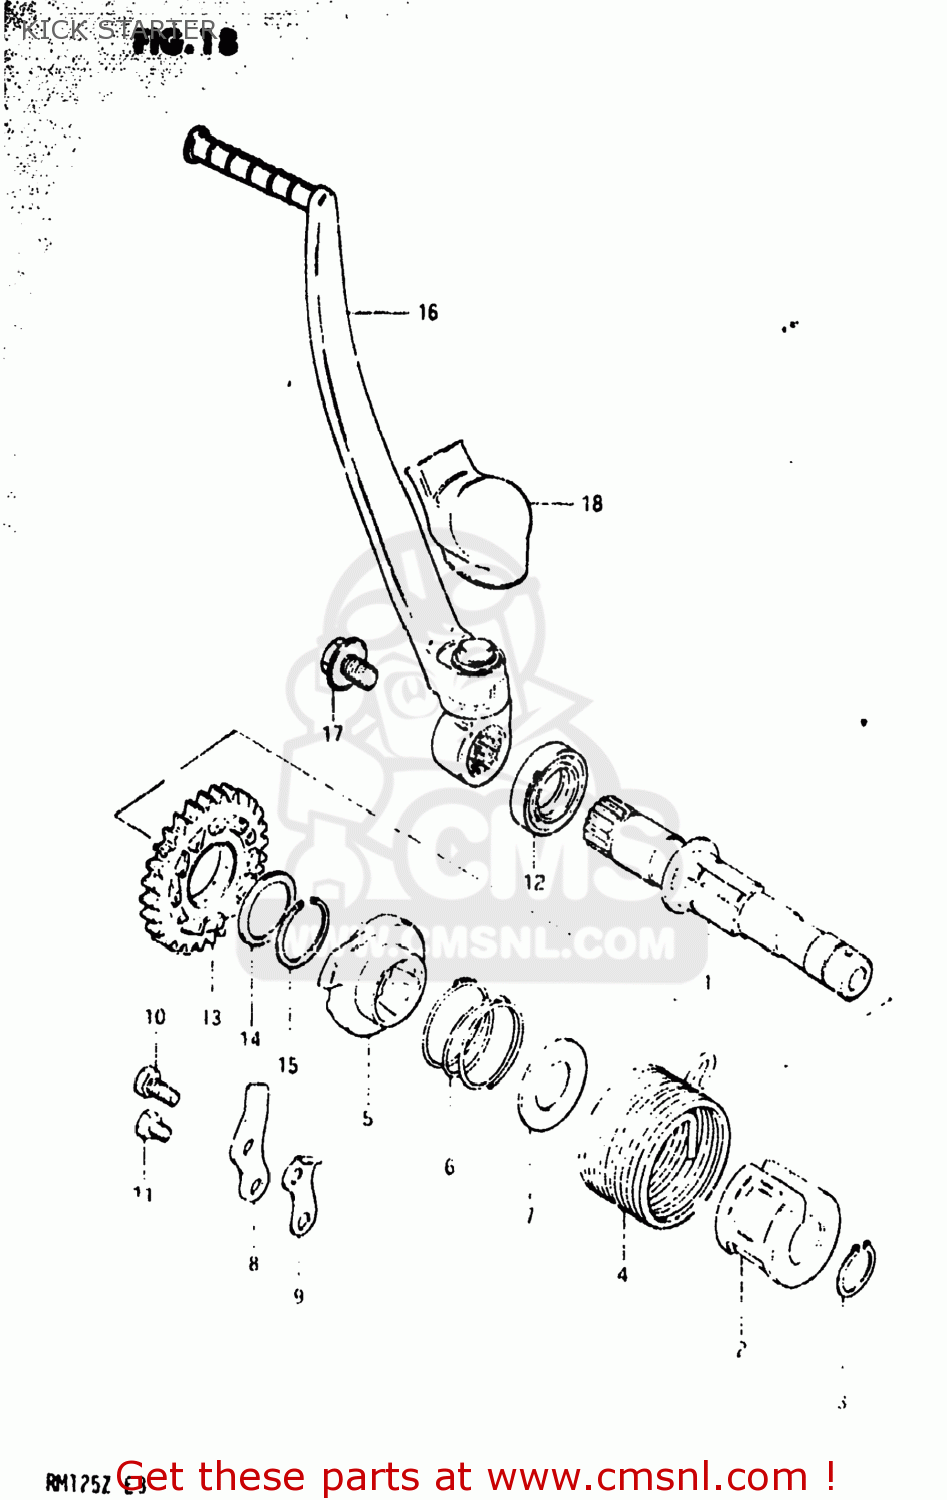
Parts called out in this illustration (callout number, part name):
1	SHAFT,KICK STARTER
2	GUIDE,KICK STARTER SFT SPRING
3	CIRCLIP
4	SPRING
5	STARTER,KICK
6	SPRING
7	WASHER
8	GUIDE,KICK STARTER
9	STOPPER,KICK STARTER
10	BOLT, UPPER
11	BOLT
12	SEAL,OIL(20X27X5)
13	GEAR,KICK STARTER DRIVE
14	SHIM
15	CIRCLIP
16	LEVER ASSEMBLY,KICK STARTER
17	BOLT(8X14)
18	COVER,KICK STARTER LEVER JOINT
